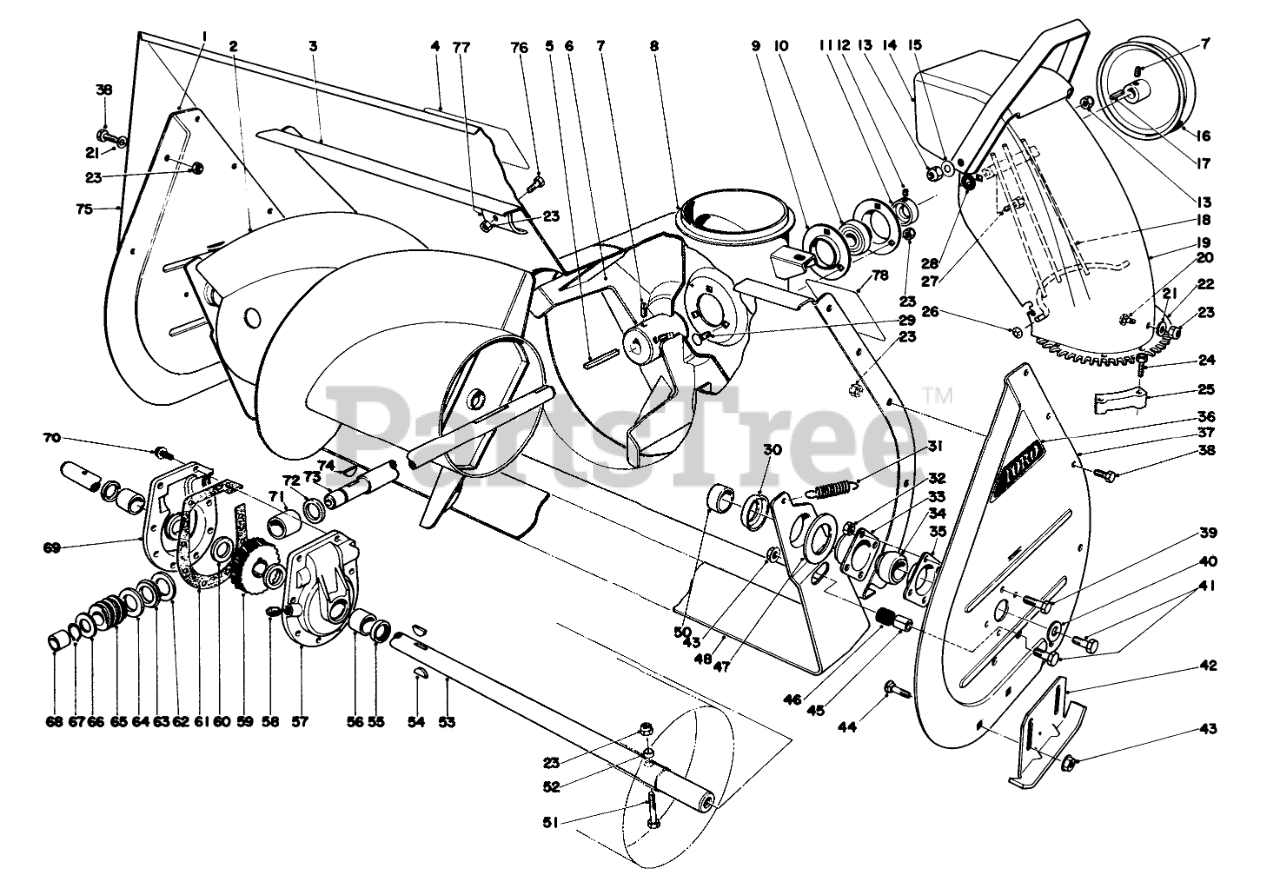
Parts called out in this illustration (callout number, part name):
1	RH AUGER SIDE PLT R
2	RH AUGER ASM - 32"
3	AUGER HSG WA 32" R
4	Decal
6	IMPELLER ASM
7	SCREW-SET, SQH
8	CHUTE RING
9	BRG FLANGE
10	BALL BRG W/COLLAR
11	EXT LOCKING COLLAR
12	SCREW-SET, HSH
13	NUT-LOCK, CONE
14	Deflector
15	WASHER-BELLEVILLE
16	1/2 X 9.5 DIA PULLEY
17	SQUARE KEY
18	Chute Wire
19	Chute-Upper
20	SCREW-CARR
21	WASHER-PLAIN
22	Screw
23	NUT-LOCK, NI
24	SCREW-SPECIAL
25	RETAINER-CHUTE
26	NUT-PUSH
27	SCREW-HH
28	WASHER-RUBBER
29	BOLT-CARR
30	Positioner-Scraper
31	SPRING-TENSION
32	NUT-LOCK, CONE
33	BEARING-FLANGE, FRONT
34	BEARING
35	BEARING-FLANGE, REAR
36	AUGER SIDE PLT DECAL
37	LH AUGER SIDE PLT R
38	SCREW-HH
39	SCREW-HH
40	WASHER
41	SCREW-HH
42	AUGER SKID WA R
43	NUT-HF
44	SCREW-CARR
45	SCRAPER STOP SPACER
46	SCRAPER STOP CUSHION
47	SCRAPER BLADE SPACER
48	SCRAPER BLADE 32" R
50	AUGER SPACER
51	Auger Bolt
52	SPACER-HUB, AUGER
53	32 AUGER SHAFT
54	KEY-WOODRUFF
55	SEAL-OIL
56	BUSHING
57	Gear Case L .H. (Incl Ref. #55-56)
58	PLUG-PIPE, SQH
59	GEAR-WORM, 27T
60	WASHER-THRUST
61	GASKET-CASE, GEAR
62	WASHER-THRUST
63	BEARING-THRUST
64	THRUST-WASHER
66	WASHER-THRUST
67	Ring-Snap
68	BUSHING
69	Gear Case R.H.(Incl. Ref. #55-56)
70	SCREW-TAPTITE
71	BUSHING-SPECIAL
72	RING-QUAD
73	SHAFT-IMPELLER
74	KEY-WOODRUFF
75	Auger Extension
76	SCREW-HH
77	SHIELD CLAMP R
78	DECAL-WARNING, AUGER
